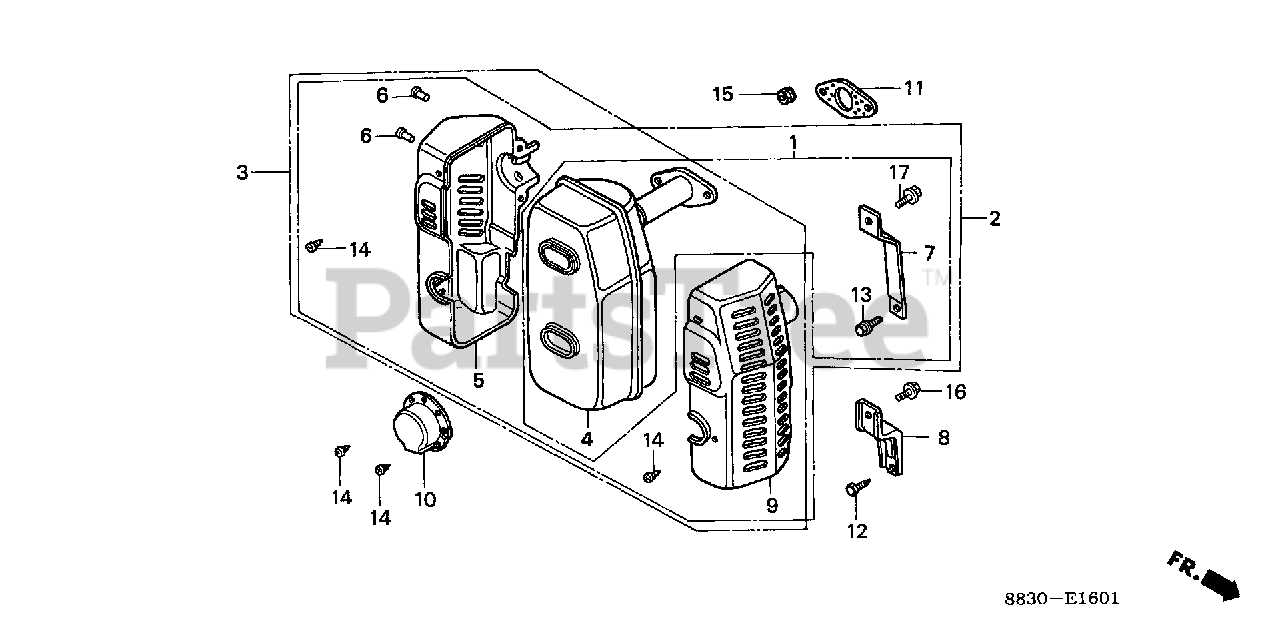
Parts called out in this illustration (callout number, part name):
1	MUFFLER KIT Use up to Engine SN 1543277.
2	MUFFLER KIT Use up to Engine SN 1543277.
3	MUFFLER ASSY.
4	MUFFLER
5	PROTECTOR, L. MUFFLER
6	RIVET (4X5)
7	STAY, MUFFLER Use up to Engine SN 1543277.
8	STAY, MUFFLER
9	PROTECTOR, R. MUFFLER
10	CAP, MUFFLER
11	GASKET, MUFFLER
12	BOLT, FLANGE (6X12) (CT200)
13	BOLT, FLANGE (8X18) Use up to Engine SN 1543277.
14	SCREW, TAPPING (4X8)
15	NUT, FLANGE (8MM)
16	BOLT, FLANGE (6X10)
17	BOLT, FLANGE (6X12) Use up to Engine SN 1543277.
